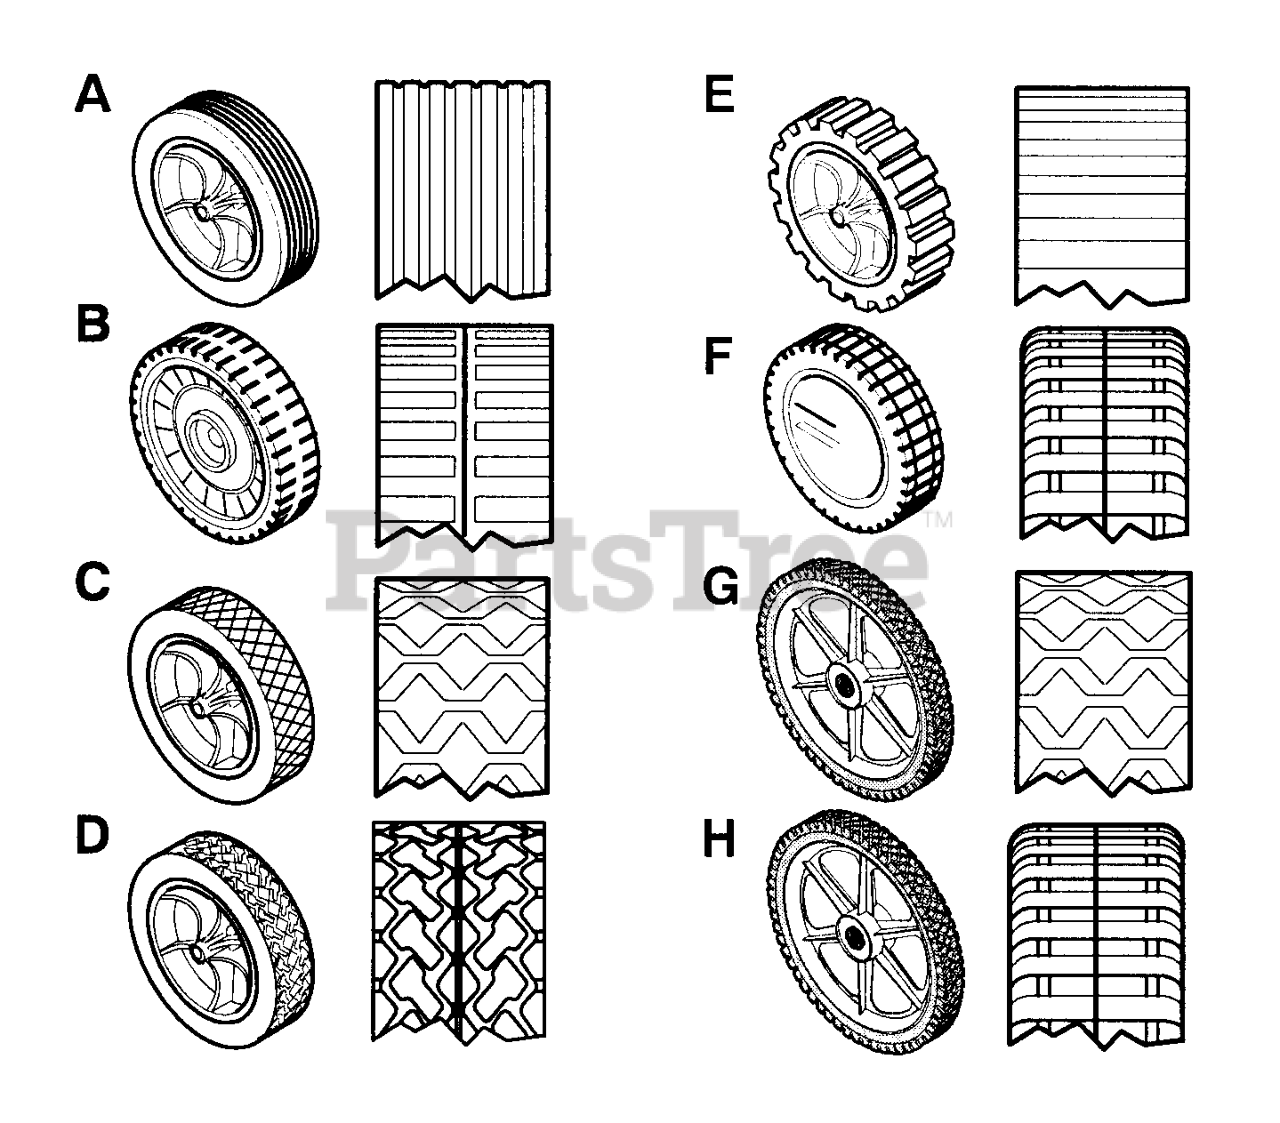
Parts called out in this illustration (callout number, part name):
A	WHEEL & TIRE ASSEMBLY, Light Gray, 8"
A	8-inch Plastic, Dark Gray
A	8-inch Metal, White
B	7-inch Plastic, White
B	7-inch Plastic, Light Gray
B	7-inch Plastic, Dark Gray
C	6-inch Plastic, White
C	7-inch Plastic, White
C	7-inch Plastic, Light Gray
C	7-inch Plastic, Dark Gray
C	8-inch Plastic, White
C	8-inch Plastic, Light Gray
C	8-inch Plastic, Dark Gray
C	8-inch Metal, White
D	7-inch Plastic, White
D	WHEEL & TIRE ASSEMBLY, White, 8"
D	8-inch Plastic, Light Gray
D	8-inch Plastic, Dark Gray
E	WHEEL & TIRE ASSEMBLY, White, 8"
E	8-inch Plastic, Dark Gray
E	8-inch Metal, White
F	WHEEL & TIRE ASSEMBLY, White, 8"
F	8-inch Plastic, Light Gray
F	8-inch Plastic, Dark Gray
F	8-inch Ball Bearing, Light Gray
F	8-inch Ball Bearing, Dark Gray
G	14-inch, White
G	14-inch, Light Gray
G	14-inch, Dark Gray
G	WHEEL & TIRE ASSEMBLY, White, 14"
G	14-in, Ball Bearing, Light Gray
G	14-in, Ball Bearing, Dark Gray
H	14-inch, White
H	14-inch, Light Gray
H	14-inch, Dark Gray
H	WHEEL & TIRE ASSEMBLY, Ball Bearing, 14"
H	14-in, Ball Bearing, Light Gray
H	14-in, Ball Bearing, Dark Gray
